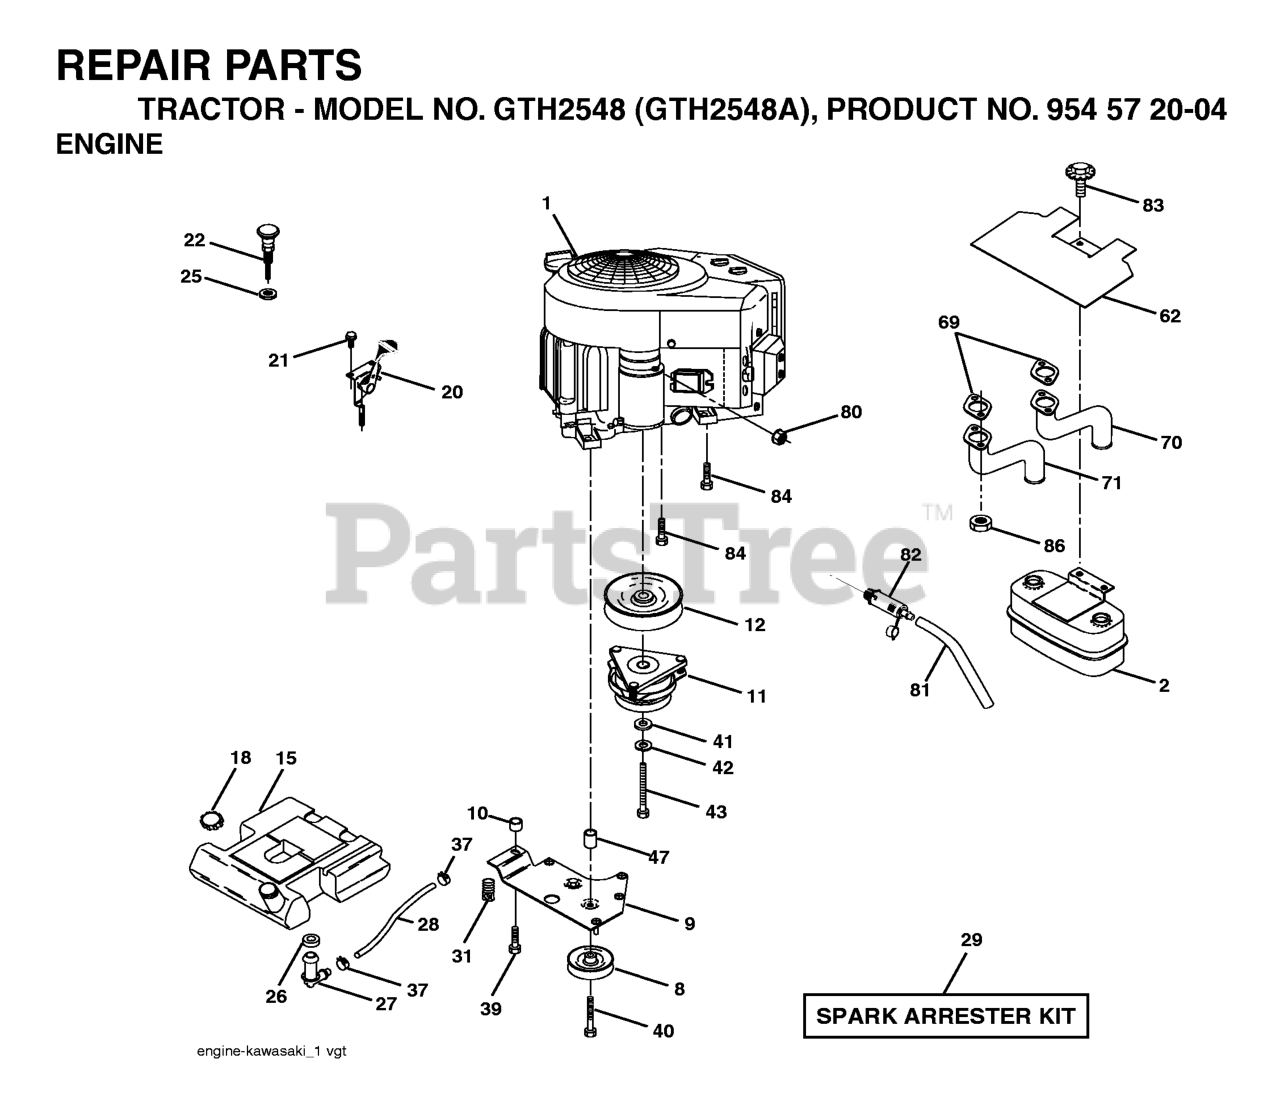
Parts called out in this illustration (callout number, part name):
2	MUFFLER.TWIN.CYL.LOW.TONE
8	RP.IDLER GROOVED
9	KEEPER ASM BELT ENGINE
11	CLUTCH MZ ZTR GT.48/54"1.125"
12	PULLEY ENG VGT ELECT CLUTCH
15	TANK.FUEL.5.0 LEFT.FILL.YTGT
18	TANK CAP
20	THROTTLE CONTROL
21	SCREW
22	CHOKE CONTROL
25	Nut Keps 3/8 - 24 UNF
26	BUSHING OUTLET T
27	STEM FUEL TANK
28	FUEL LINE
29	KIT.SPARK ARRESTOR 794945 B&S
37	HOSE CLAMP
39	SCREW TT 3/8-16X2-1/4 UNC
40	Screw TT 3/8-16 x 4 unc
42	LOCKWASHER
43	BOLT HEX 7/16-20 X 3.75 GR. 5
62	RP SHIELD HEAT MUFFLER
80	FLANGE NUT
81	TUBE, DRAIN OIL ASM.
83	BOLT.5/16-18UNCX3/4 W/SEMS.BLK
84	SCREW 3/8-16 X 1-1/2
86	NUT.HEX.FLANGE.TOPLOCK
